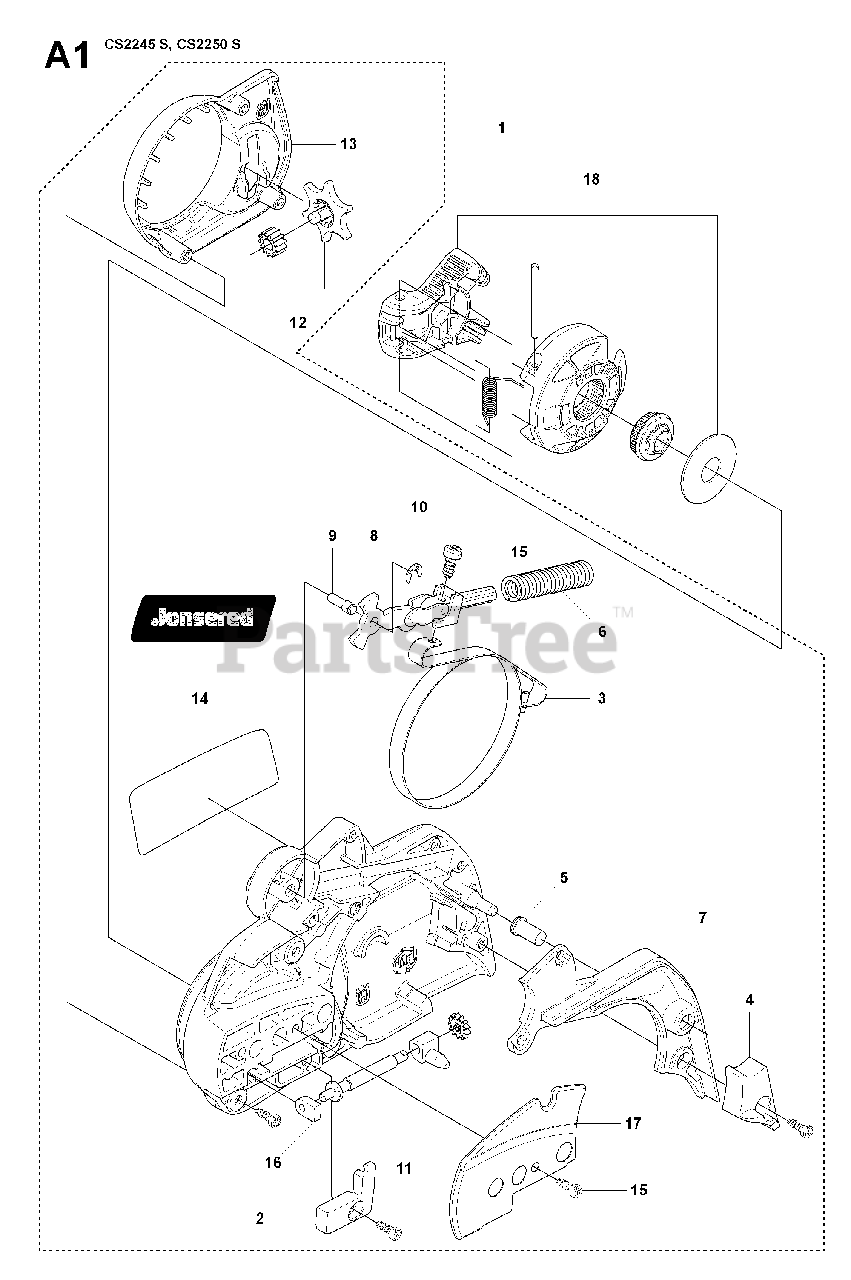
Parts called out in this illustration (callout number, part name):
1	CLUTCH COVER ASSY
2	%COVER
3	BRAKE BAND
4	WEAR GUARD, CHAIN
7	COVER, CHAIN BRAKE
11	CHAIN TENSIONER SCREW, COMP.
12	CHAIN TENSIONER WHEEL
16	RP BEARING SLEEVE
